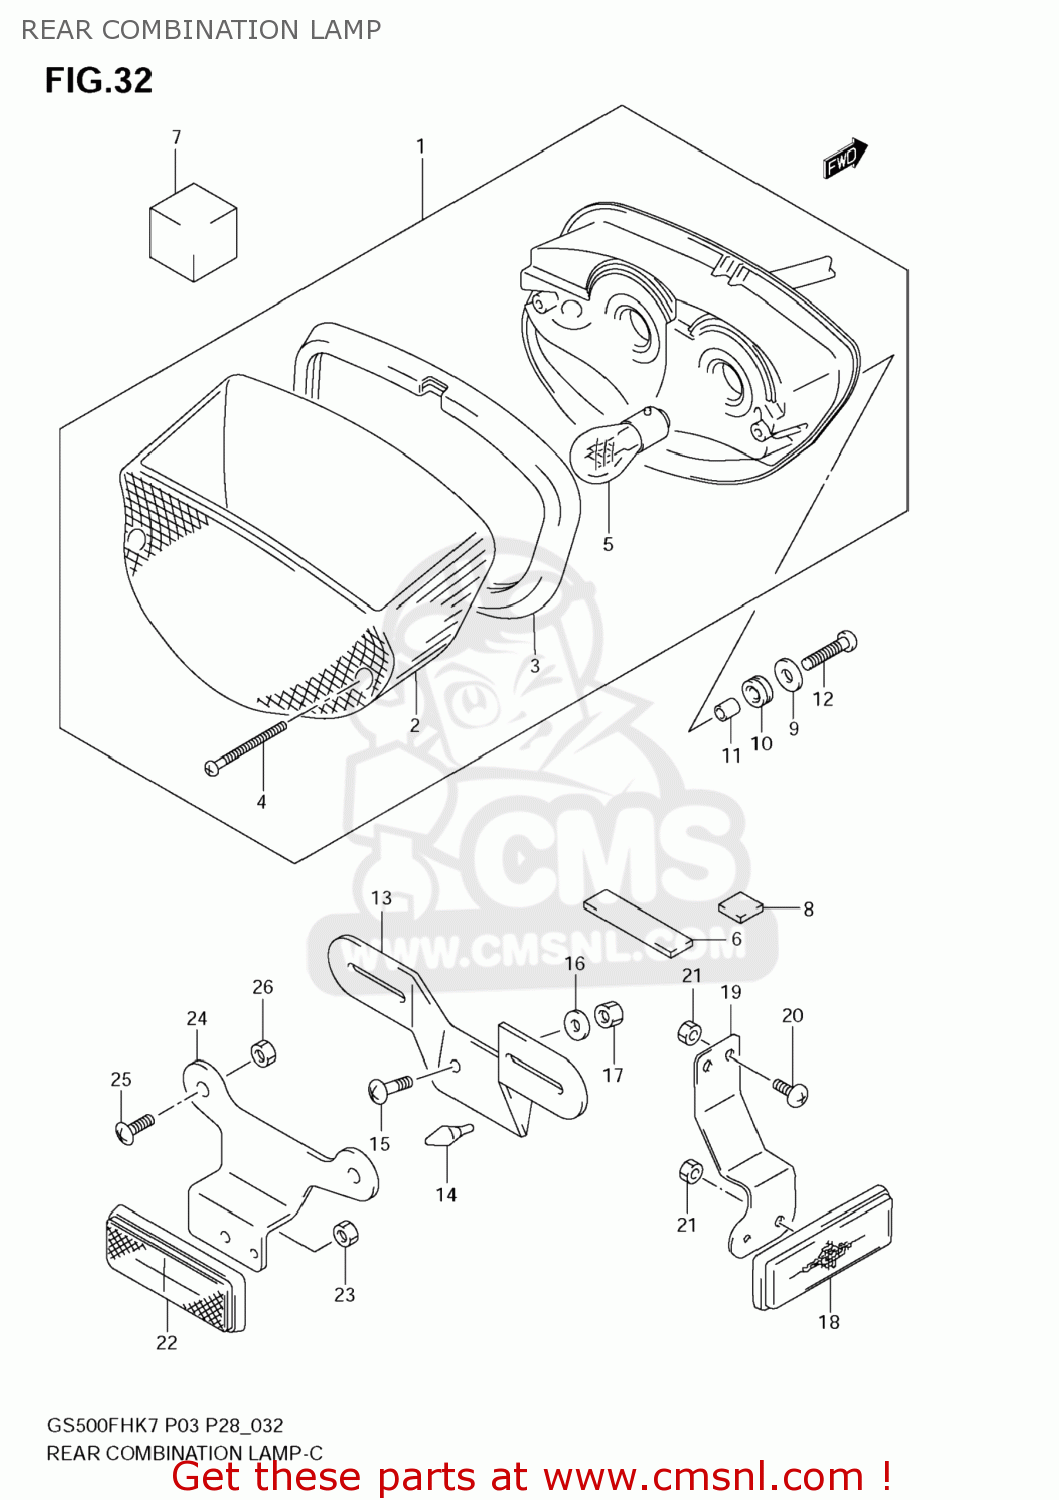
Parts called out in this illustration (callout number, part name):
1	LAMP ASSY,RR COMBINATION
2	LENS
3	GASKET,LENS (NAS)
4	SCREW
5	BULB(12V32/3CP)
6	CUSHION (80X20X10)
7	CUSHION, UPPER (40X40X38)
8	CUSHION, LOWER (20X20X6)
9	WASHER
10	CUSHION
11	SPACER(6.5X9X8.5)
12	SCREW
13	BRACKET,LICENSE PLATE
14	CUSHION
15	SCREW
16	WASHER
17	NUT
18	REFLECTOR ASSY,RR
19	BRACKET,RR SIDE REFLECTOR
20	SCREW
21	NUT
22	REFLECTOR ASSY,RR
23	NUT
24	BRACKET,RR RR
25	SCREW
26	NUT
